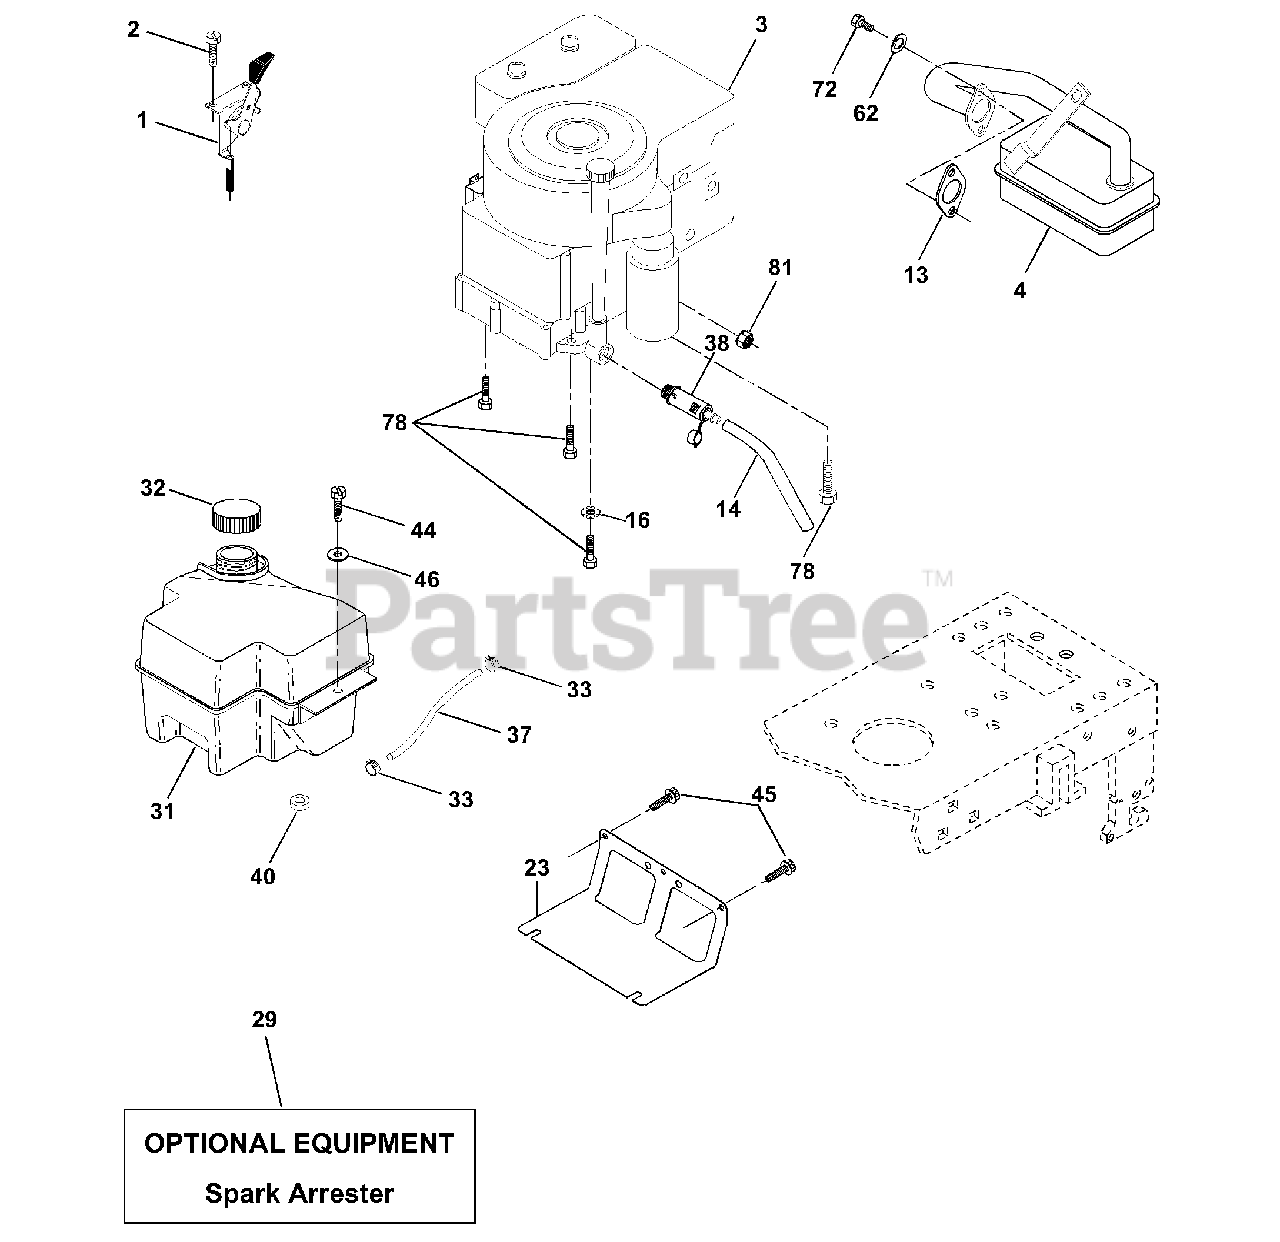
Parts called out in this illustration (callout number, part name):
1	Control Th/ch Flag Dom.
2	Screw Hex Thd Cut 1/4-20x5/8 T
3	Engine B&S
13	Gasket
14	Tube Drain Oil Easy
16	Washer Lock Ext Tooth 3/8
23	Shield BRN/DBR Guard
29	Kit Spark Arrestor (Flat Scrn)
31	Tank Fuel
32	Cap Asm Fuel W/sym Vented
33	Clamp Hose Black
37	Line Fuel
38	Plug Drain Oil Easy
40	Bushing Snap Nyl Blk Line Fuel
44	Screw Hex Wsh Thdrol 1/4-20 x 3/4
45	Screw Hex Wsh Thdrol 3/8-16 x 3/4
46	Washer 9/32 x 7/8 x 16 Ga.
62	Washer Lock Hvy Hlcl Spr. 5/16
72	Screw Hex Hd Cap 5/16-18 x 3/4
78	Screw 3/8-16 x 1-1/4
81	Nut Keps Hex 1/4-20 Unc
